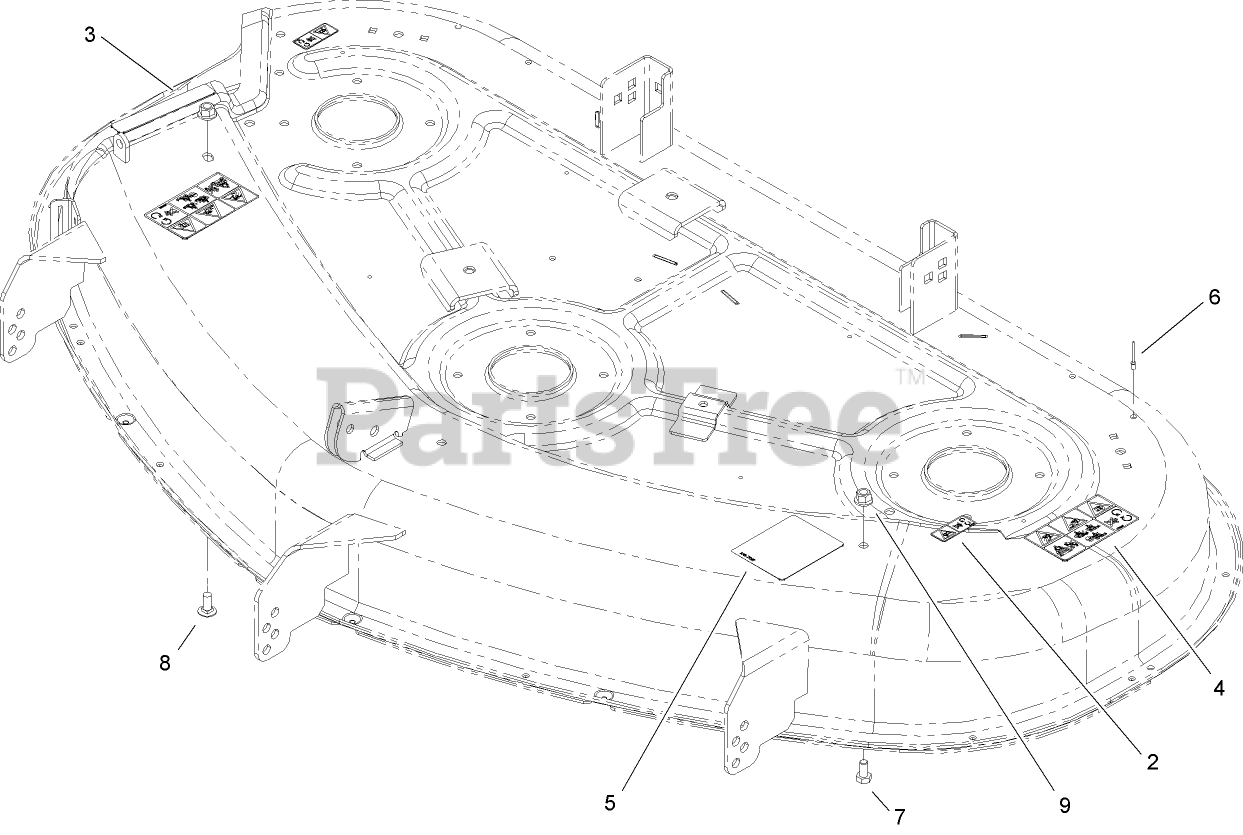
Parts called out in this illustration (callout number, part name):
2	DECAL-DANGER
3	DECAL-DANGER
4	DECAL-DANGER
5	DECAL-ROUTING, BELT
6	RIVET-BLIND
7	SCREW-HH
8	SCREW-CARR
9	NUT-LOCK, NI
